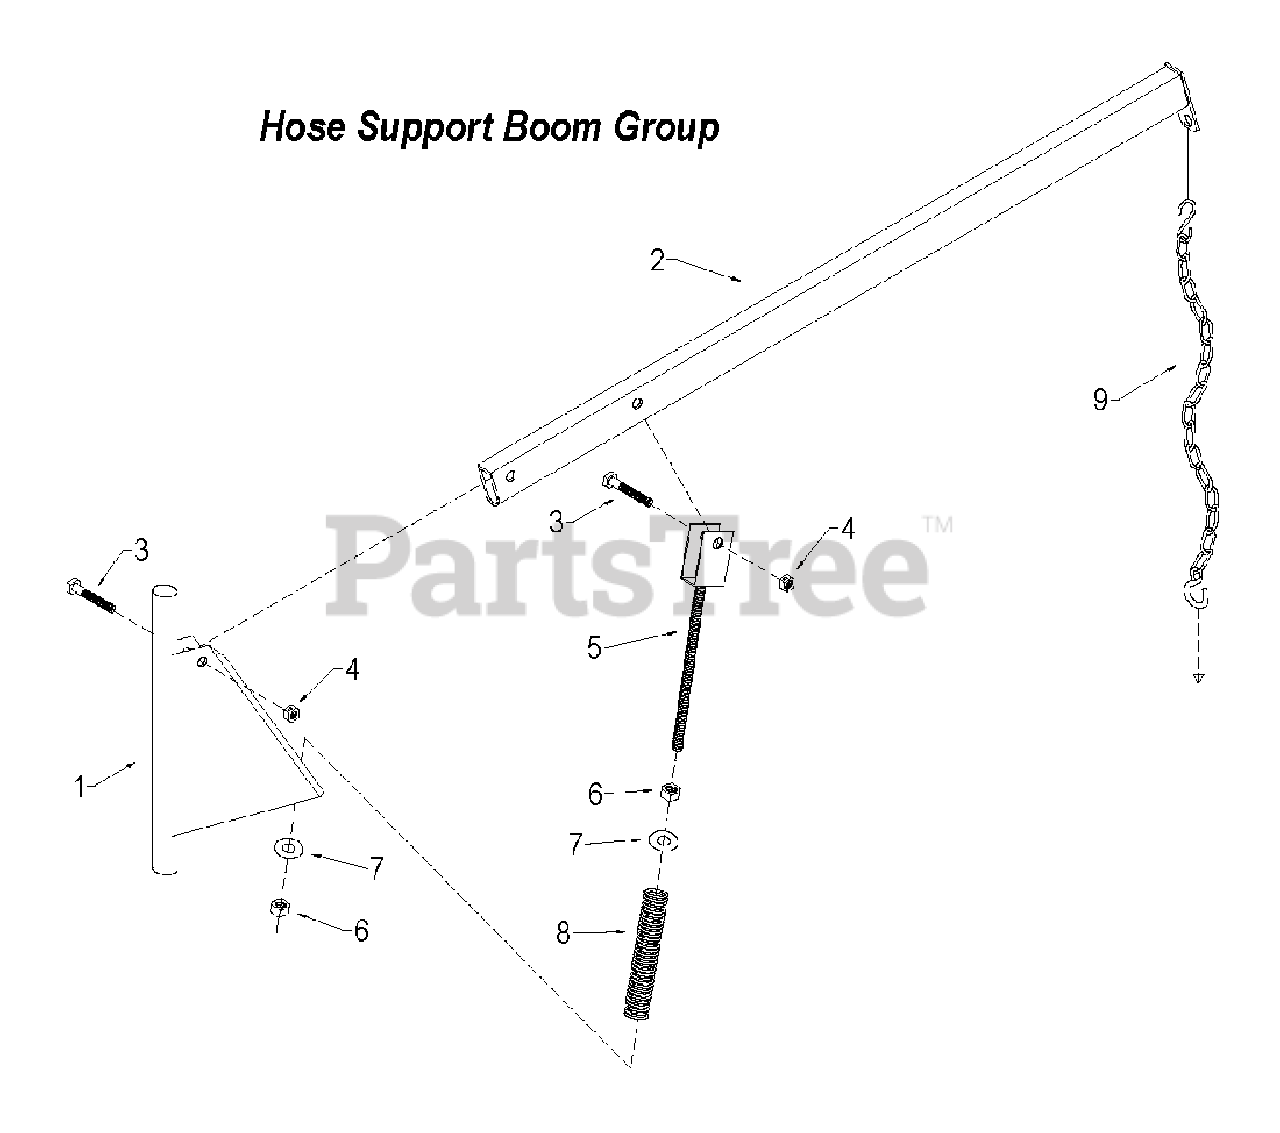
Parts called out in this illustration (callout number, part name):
1	Boom vertical member
2	Boom horizontal member
3	Bolt, hex – 1/2-13 x 3"
4	Nut, reverse lock – 1/2-13
5	Guide, threaded spring
6	Nut, hex – 3/4-10
7	Washer, flat – 3/4"
8	Spring, boom
9	Chain, boom – 48 w/2 S-hooks
